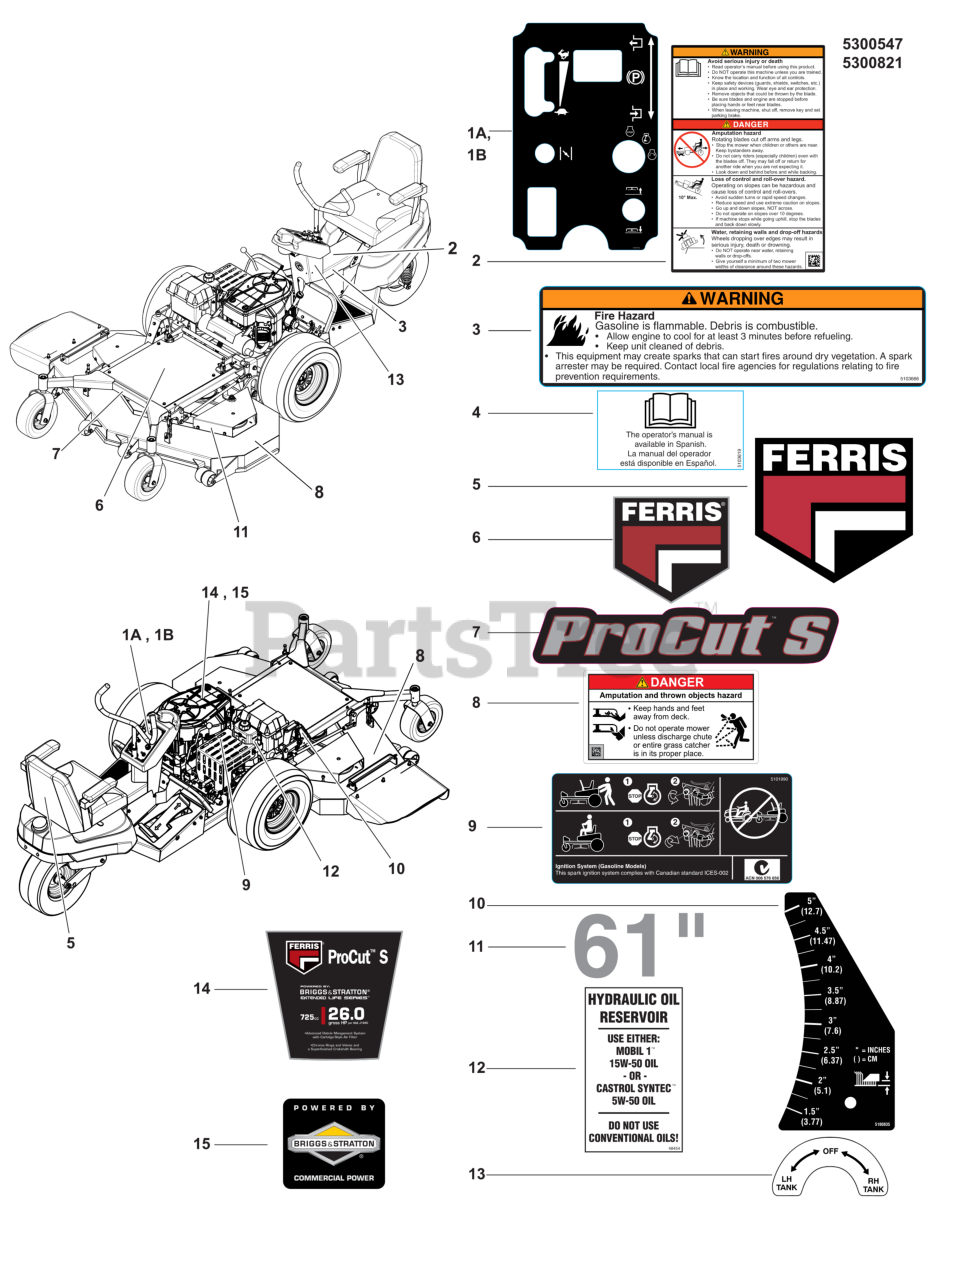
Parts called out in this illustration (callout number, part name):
1A	DECAL, DASH, TWR
1B	DECAL, CONTROL PANEL - TWR
3	DECAL, FIRE HAZARD, 6.75W X 1.75H
4	DECAL, MANUAL AVAIL IN SPANISH
5	DECAL, FERRIS LOGO, 9-3/8
6	DECAL, BRAND
7	DECAL, MODEL
8	DECAL, Danger
9	DECAL, CZT HYDRO RELEASE
10	DECAL, CUT HEIGHT, TWR
11	DECAL, 61"
12	DECAL, OIL RESERVOIR
13	DECAL, FUEL VALVE
14	DECAL, PROCUT S
